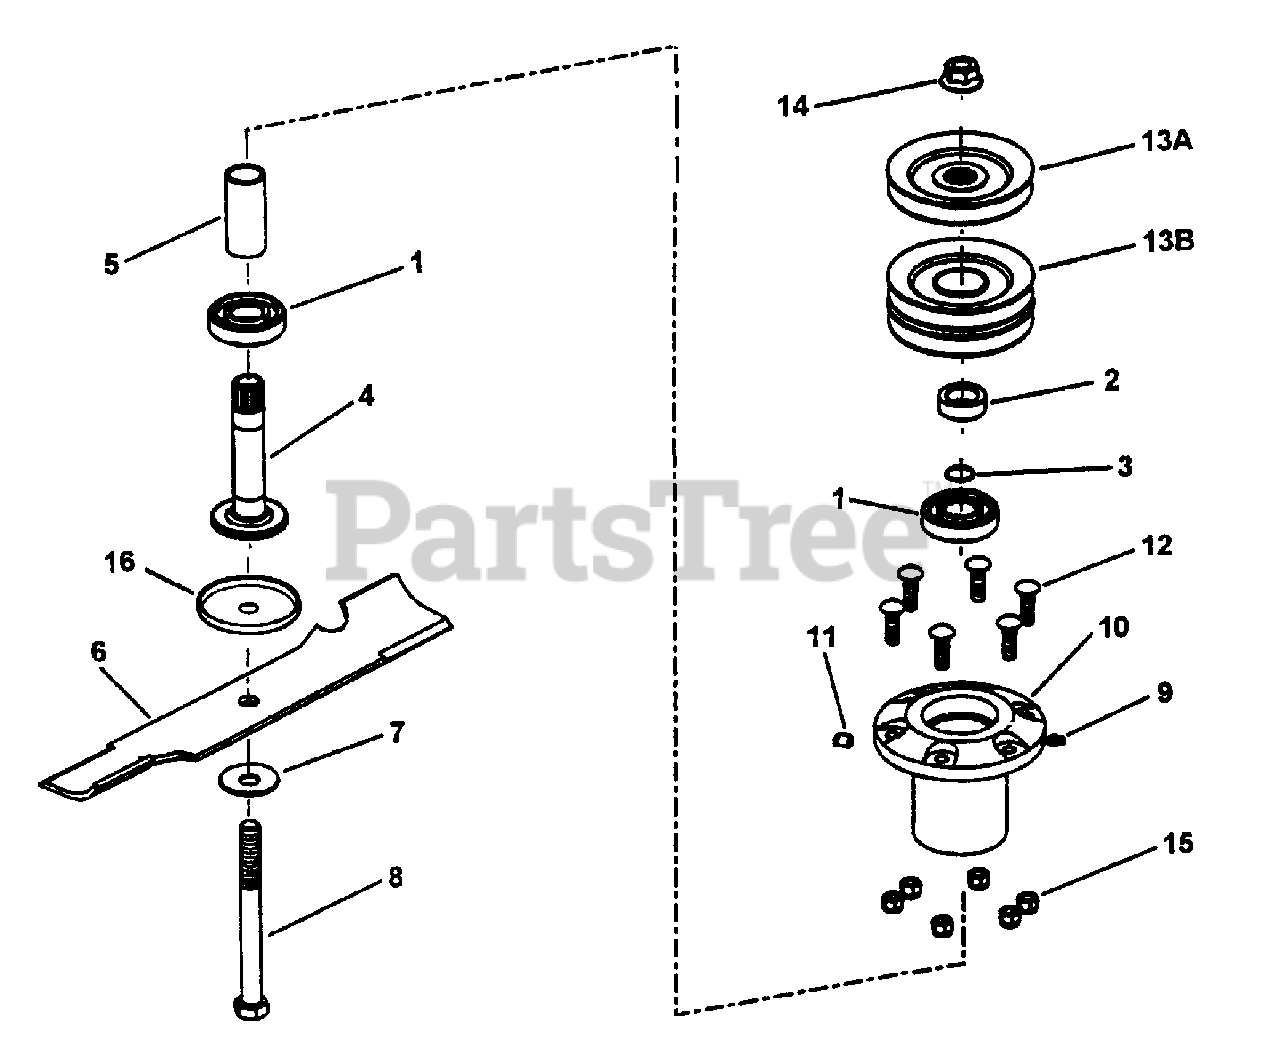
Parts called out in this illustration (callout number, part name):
1	BEARING, Sealed
2	WASHER, Spindle
3	SNAP-RING, Spindle Shaft
4	SHAFT, Spindle
5	SPACER, Bearing
6	BLADE, 16-1/2"
7	WASHER, Beveled
8	BOLT, 5/8-18 x 6-5/8" Hex Head, Grade 5
9	LUBE FITTING, 1/4-28 Thread Forming
10	HOUSING, Cutter
10	SPINDLE HOUSING, sub assembly
11	VENT, Spindle
12	BOLT, 3/8-16 x 1-1/4" Rib Necked
13A	PULLEY, Spindle
13B	PULLEY, Spindle
14	NUT, 5/8-18 Hex Flange Lock, Grade 5
15	NUT, 3/8-16 Hex Nyloc
16	CUP, Spindle Cover
